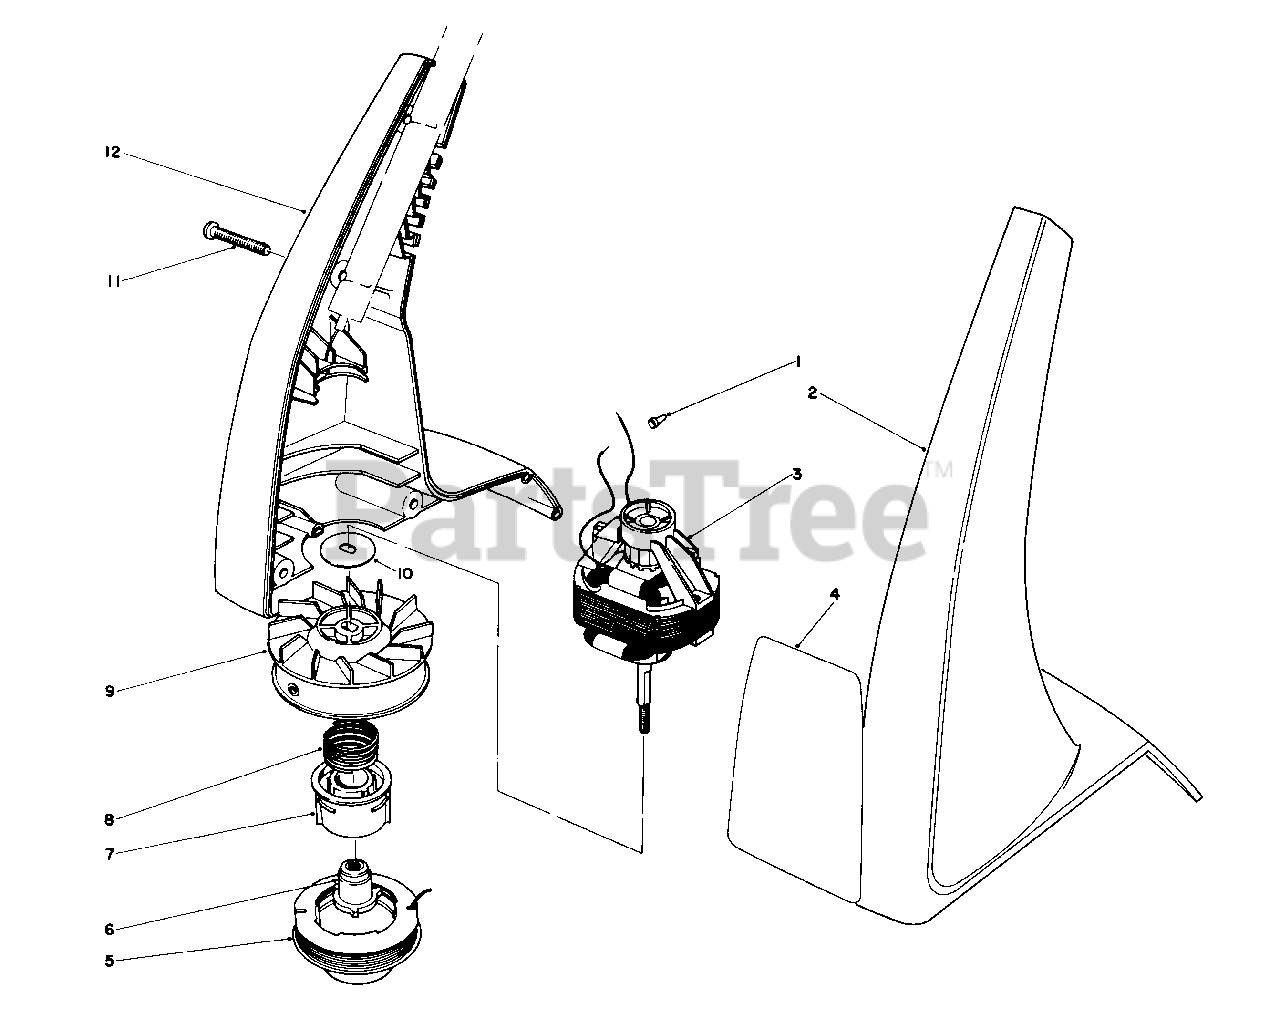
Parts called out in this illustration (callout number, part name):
1	Connector-Wire
2	Housing-L.H.
5	12 Ft. .050 Dia. Cutting Line Prewound on Spool
7	Spool Core
9	Drum w/Eyelet
10	Washer-Motor
11	Screw
12	Housing-R.H.
